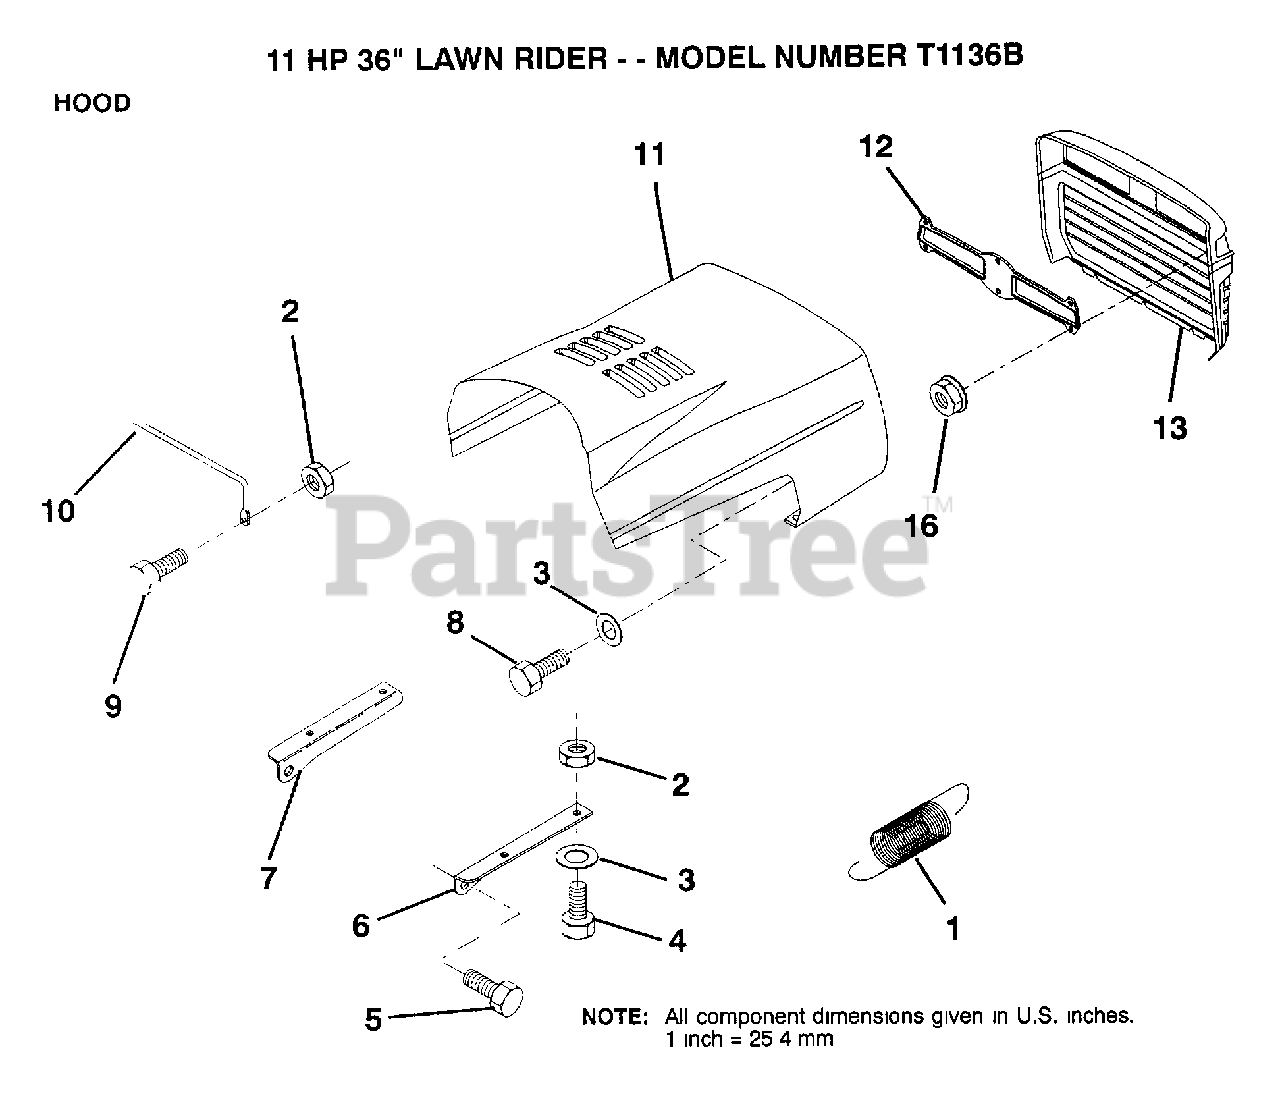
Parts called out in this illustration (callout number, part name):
1	EXT SPRING
2	NUT
3	WASHER
4	BOLT
6	BRKT HOOD RH
7	BRKT HOOD LH
10	"BRACE,HOOD"
11	HOOD
16	NUT
